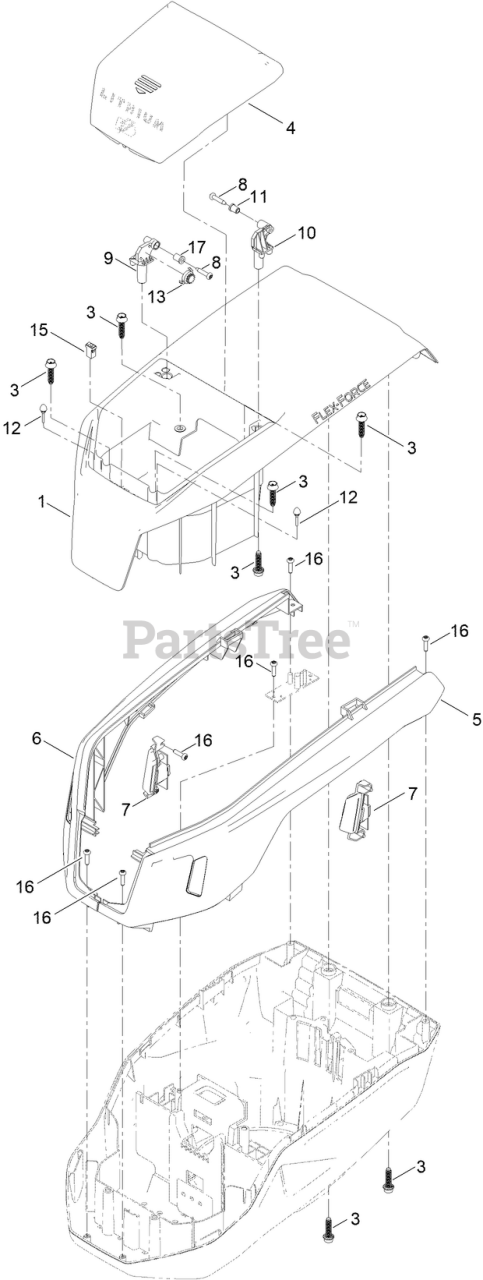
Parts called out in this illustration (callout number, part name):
1	SHROUD-UPPER
3	SCREW-FLANGE, PLASTIC
4	DOOR-BATTERY
5	BEZEL-LH
6	BEZEL-RH
7	LED ASM
9	PIVOT-DOOR, BATTERY
10	PIVOT-DOOR, BATTERY
11	BUSHING-SPACER
12	BUMPER-RUBBER
13	DAMPER-GEAR
15	LATCH-PUSH
16	SCREW-TORX DRIVE PLASTITE
17	BUSHING-SPACER, METAL
